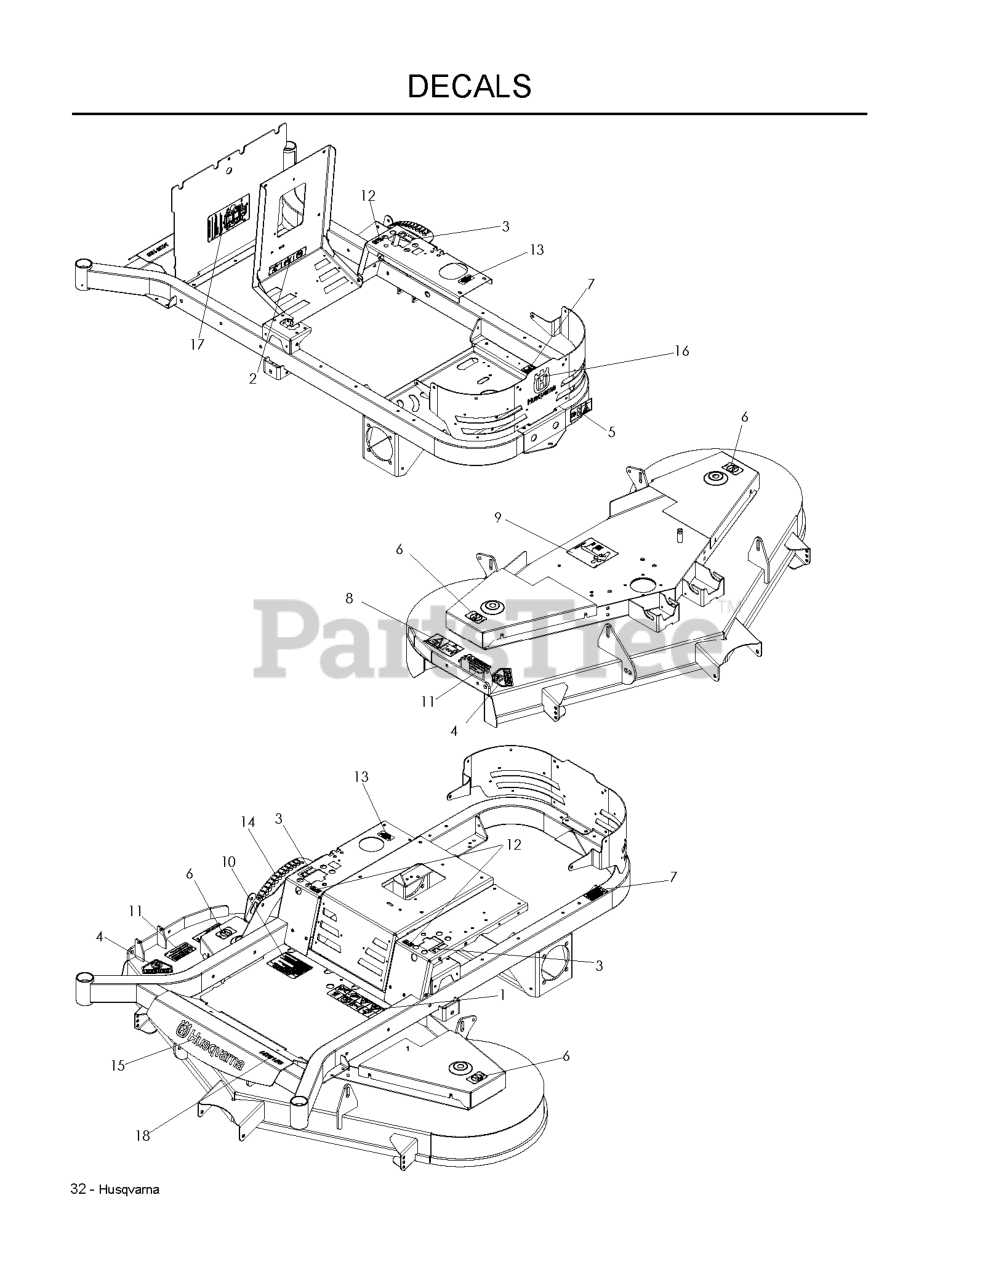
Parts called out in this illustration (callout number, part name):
1	DECAL, WARNING
2	EURO DECAL-BATTERY WARNIN6
3	DECAL, MOTION CONTROL
4	DECAL, CPSC
5	DECAL, BELT DRIVE
6	DECAL, NO STEP
7	DECAL, PROP. 65
8	DECAL, EURO SEVERING
9	RP DECAL, BELT ROUTING
10	DECAL, WARNING
11	DECAL, CAUTION
12	DECAL, F.S.T.
13	DECAL, OIL TANK
14	DECAL, HEIGHT ADJUST
15	DECAL, HUSQ 12" BLUE
16	DECAL, CROWN H BLUE
17	DECAL, SERVICE
18	DECAL, MZ5225
